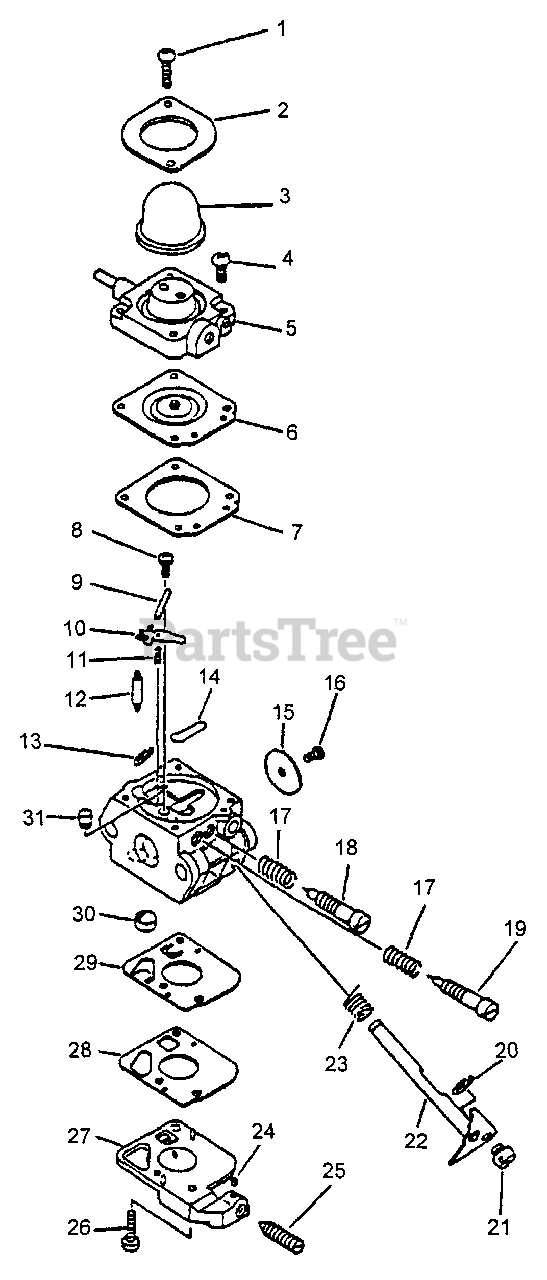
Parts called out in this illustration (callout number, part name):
2	RETAINER
3	BULB, PURGE
5	BODY ASSY, PURGE
6	DIAPHRAGM, METERING
7	GASKET, METERING
8	SCREW
9	PIN
10	LEVER, METERING
11	SPRING, METERING LEVER
12	VALVE, NEEDLE
14	PLUG, WELCH
15	VALVE, THROTTLE
17	SPRING, NEEDLE
18	NEEDLE, IDLE
19	NEEDLE, HIGH SPEED
22	SHAFT, THROTTLE
23	SPRING, THROTTLE RETURN
24	PIECE, FRICTION
25	SCREW, IDLE ADJUST
27	COVER, PUMP
30	STRAINER
31	NOZZLE, CHECK VALVE
